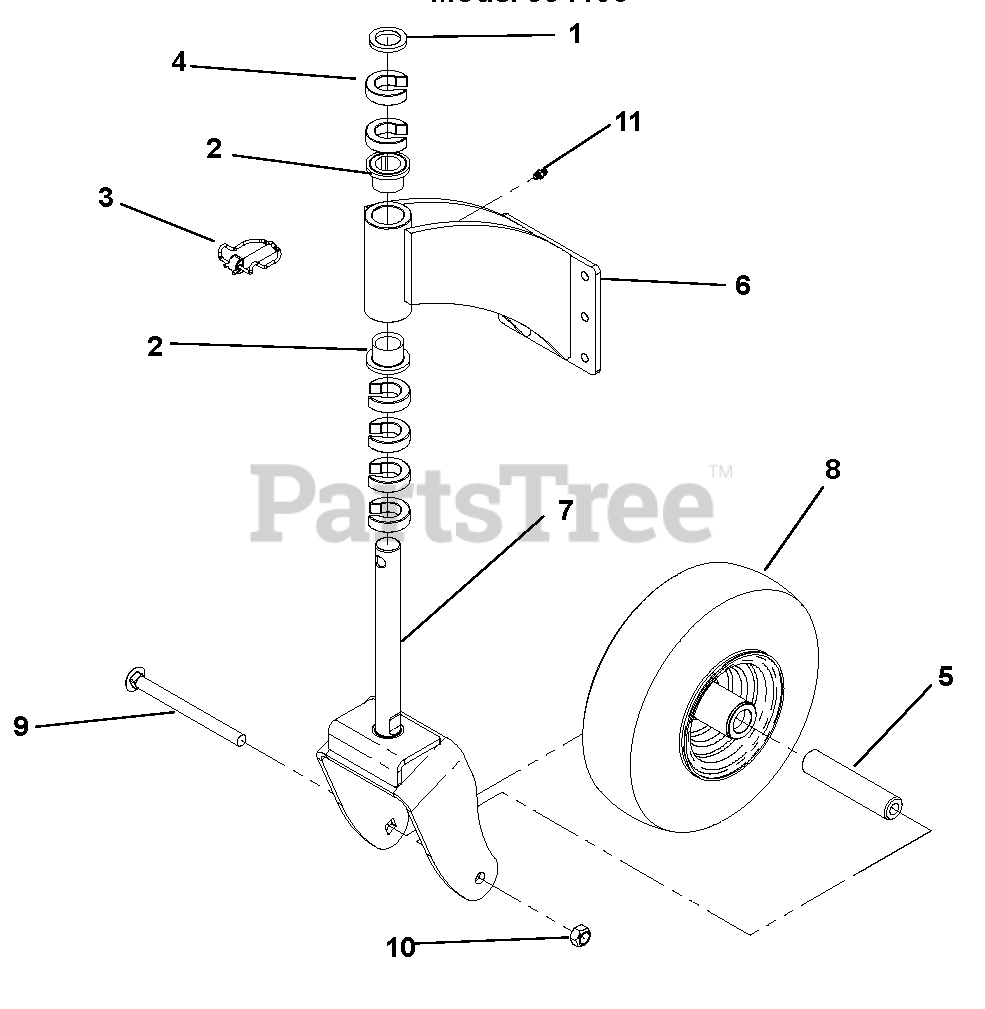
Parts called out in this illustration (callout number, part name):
1	Bushing, 1.03 x 1.50 x .179
2	Bearing, Flange 1.00 x 1.25 x 1.00
3	Pin, Lock .438 x 2.00
4	C-Spacer, 1.00 x 1.77 x .50
5	Tube, 1.00 x .50 x 4.76
6	Weldment, Caster Mount Bracket
7	Weldment, Front Wheel Fork
8	Wheel, Front 11 x 4 x 5
9	Bolt, .50-13 x 6.00 Round Head Square Neck
10	Locknut, .50-13 Crown
11	Grease Zerk, .1/4-28 Straight .69 LG
